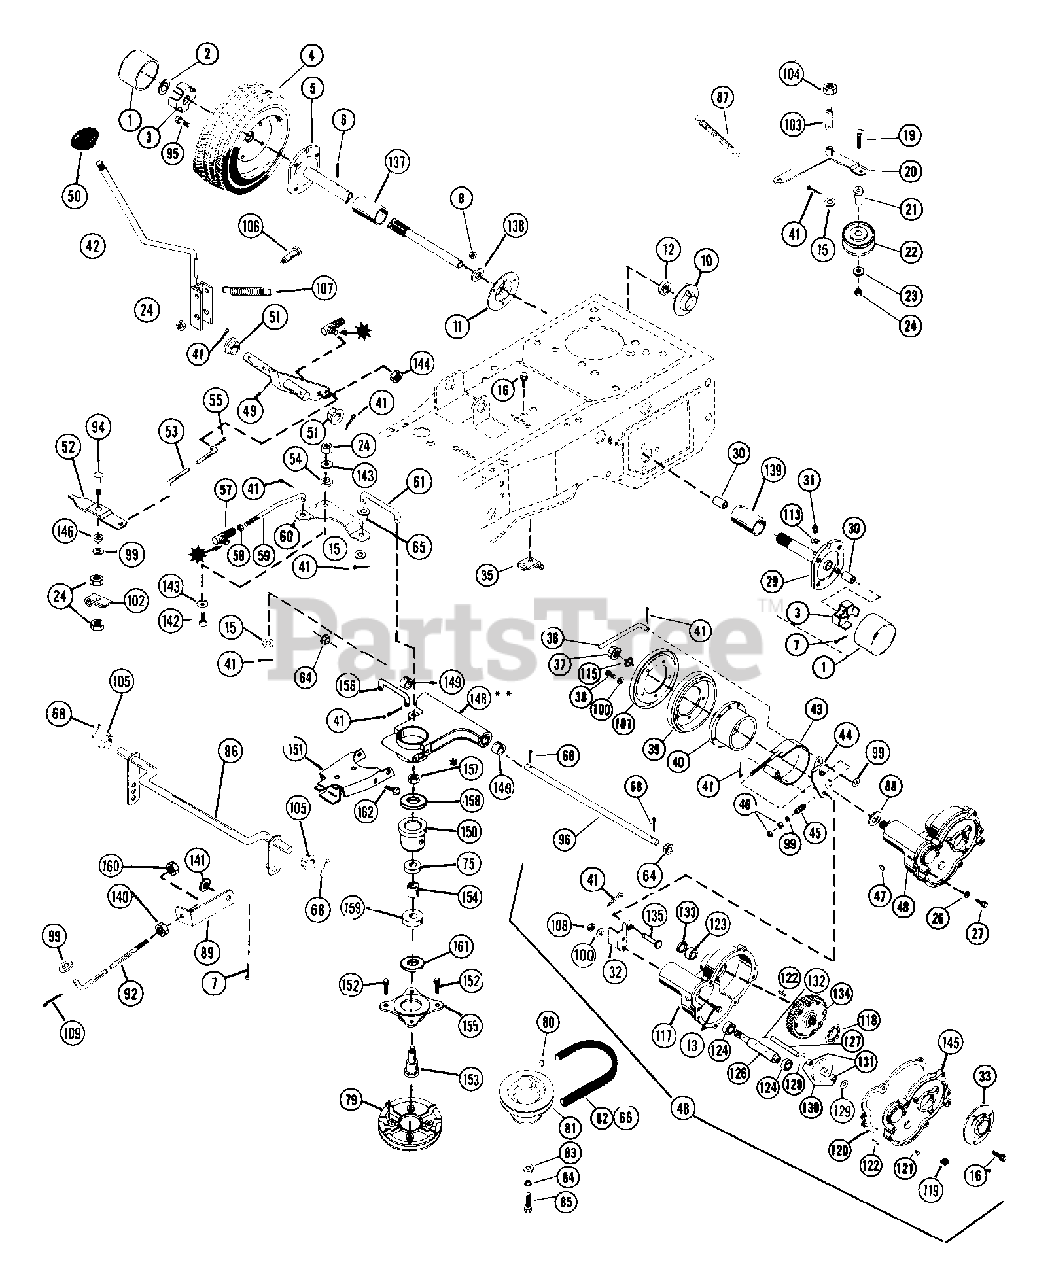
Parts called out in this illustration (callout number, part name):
1	HUB CAP
2	PUSHNUT
3	SPINDLE CUP
4	WHEEL ASSEMBLY
4	TIRE
4	TERRA TIRE & WHEEL ASSEMBLY
4	TIRE 16X6.50-8 2 PLY
5	R H AXLE
5	RH AXLE
6	PIN-ROLL .188X1.25
7	PIN-COTR .12X1.0 PL
8	NUT-LK-FLG .250-20 PL
10	BEARING FLANGE
11	BEARING FLANGE
12	BRG-BALL .876 X 1.750 X .50
13	BLT-SERRDHD SL .31-18X.75 YZ
15	WSHR-FL-STL .505X.880X.072 PL
16	BLT-SCRHFWH .25-20X.62 PL
19	BLT-RDHDSQNK .31-18X1.25 SHTPL
20	IDLER ARM
21	SPACER -SHLD .344X.500X.469
22	IDLER
23	WSHR-FL-STL .38X.875X.083 PL
24	NUT-LK .312-18 GR A PL
25	WSHR-FL-STL .391X1.500X.188 PL
26	WSHR-LK .312X.097 PL HVY
28	BLT-HEX .31-18X.75 PL GR5
29	L H AXLE ASSEMBLY
30	BSHG-SLV .690X.814X1.000 BR
31	SPIN DRIVE ZERK FITTING
32	BRAKE BRACKET
33	SEAL 1.125X2.496X.380
35	NEUTRAL STOP
36	BRAKE ROD
37	NUT-LK-NYL.625-18 PL
38	BLT-HEX .31-18X.50 PL GR2
39	FRICTION DISC
40	FRICTION DISC HUB
41	PIN-COTR .09X.75 PL
42	SHIFT LEVER
43	BRAKE BAND
44	BRAKE LEVER
45	SG-COMP .105X.585X.75
46	NUT-HEX .312-18
46	WIRE
47	KEY-WDRF .188X.875X.375 SAE11
48	GEAR CASE ASSEMBLY
49	SHIFT ARM
50	SHIFT BALL
51	FLANGE BUSHING
52	INDICATOR
53	INDICATOR ROD
54	SPACER BUSHING .5 X .32 X .21
55	PIN-COTR .06X.50
56	NUT-LK-CTR .312-24 PL
57	SNAP IN BALL JOINT
58	NUT-HEX .312-24 PL
59	SHIFT ROD
60	BELL CRANK
61	SHIFT LINK
63	SCR-TAP .312-18X.50 HWH PL TR
64	FLANGE BUSHING
65	BSHG-FLG .372X.500X.312X.625NY
67	WSHR-FL-STL .328X.875X.062 PL
68	PIN-COTR .12X1.0 PL
69	BLT-HEX .50-20X3.50 PL GR2
75	BRG-BALL .625X1.375X.44
80	KEY-STR .25X2.0X.25
81	ENGINE SHEAVE
82	V-BELT, 3L-RAW EDGE
83	WSHR-FL-STL .505X1.140X.250
84	WSHR-LK .438X.133 HVY
85	BLT-HEX .38-24X1.25 BLKO GR5
86	CLUTCH SHAFT
87	SG-TENS 5.65 FREE LENGTH
88	WSHR-FL-STL .627X.990X.032
89	CLUTCH BRACKET
92	ROD, CLUTCH
94	BLT-RDHDSQNK .31-18X1.0 SHT PL
95	BLT-WHL .50-20X.75 GR5 PL
96	TRANSFER SHAFT
99	WSHR-FL-STL .323X.625X.062 PL
100	WSHR-LK-INT .313X.030 PL
103	SHOULDER STUD
104	NUT-LK-CTR .375-16 GR A PL
105	FLANGE BUSHING
106	SHOULDER BOLT .436 X .912
107	SG-TENS .092X.69X1.75 WLD 54
108	NUT-HEAVY .312-18 PL
109	PIN-COTR .12 X 1.25 PL
113	WSHR-LK .250X.047 LT PL
115	WSHR-LK-INT .625X.045 PL
117	SERVICE GEAR CASE
118	BRG-BALL 1.125X2.50X.63
119	BREATHER
120	GASKET
121	SCR-FLG-WHZ 10-24X.75 PL
122	PIN-GRV .188X.63
123	BSHG-SLV .875X1.125X1.046
124	BRG-BALL .625X1.375X.44
126	PINION SHAFT
127	IDLER SHAFT
129	WSHR-FL-STL .505X.875X.024 PL
130	PINION & GEAR W/BEARING ASSEMB
131	BRG-NEEDLE .50X.688X.625
132	PIN-ROLL .125X.75
133	SEAL .875X1.125X.125
134	DIFFERENTIAL ASSEMBLY
135	PIN-CLEV .371X3.25
137	TUBE .875 X 1.875 X 4.500
138	WSHR-FL-STL .880X1.380X.062
139	TUBE 1.125 X 1.875 X 4.500
139	TUBE
140	NUT-HEX .312-18
141	WSHR-FL-STL .531X1.062X.095 PL
142	BLT-HEX .31-18X.75 PL GR2
143	WSHR-FL-STL .344X1.125X.063PL
144	NUT-LK-CTR .312-24 PL
145	GEAR CASE COVER ASSEMBLY
146	SPACER
147	BLT-SERHFWH .31-18X.75 PL
148	CARRIER ASSEMBLY
149	BSHG-SLV .625X.750X.500 BR
150	BEARING HOUSING
151	CARRIER YOKE
152	BLT-SERHFWH .25-20X.50 PL
153	SPINDLE BOLT
154	BSHG-SLV .634X1.000X.465
155	DISC ADAPTER
156	SHIFT LINK
157	NUT-LK-CTR .50-20 PL
158	WSHR-HDND-STL-THR.515X.97X.062
159	BRG-BALL .750X1.781X.61
160	NUT-LK-NYL.312-18 PL
161	WSHR-HDND-THRST .758X1.23X.031
162	BLT-SERHFWH .31-18X.75 PL
